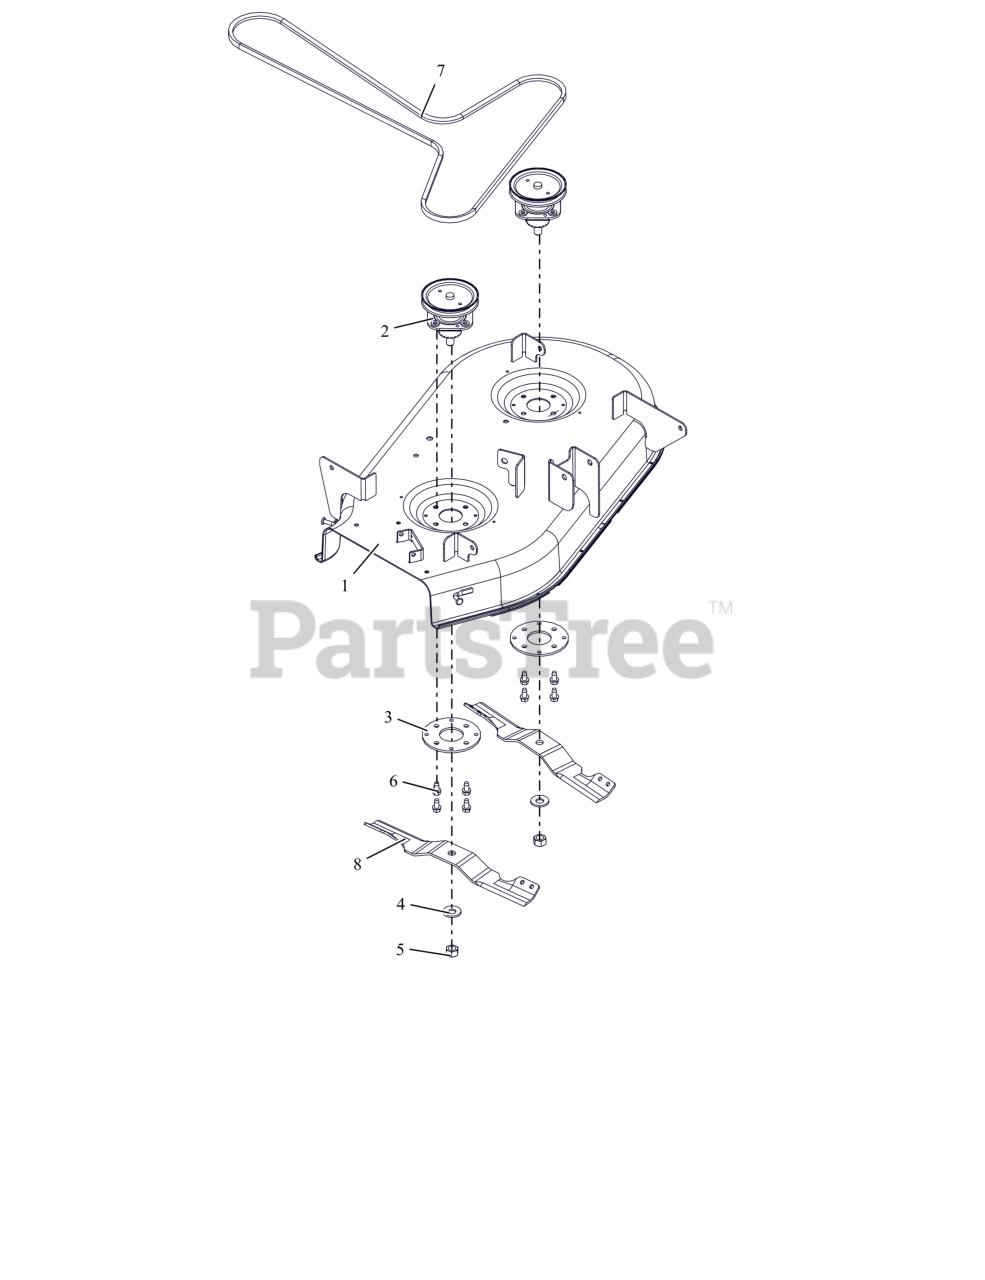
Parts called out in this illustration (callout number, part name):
1	KIT, 34" ARIENS DECK W/DECALS
2	KIT, DECK SPINDLE ASM (34/50)
3	PLATE-REINF, SPINDLE
4	WSHR-BLVL .669X1.535X.138
5	NUT-STD .625-18 ZCC
6	SCR,TAP .375-16X.75 HWH TR ZCC
7	V-BELT, HA-WRAPPED
8	BLADE, MOWER 17.35
